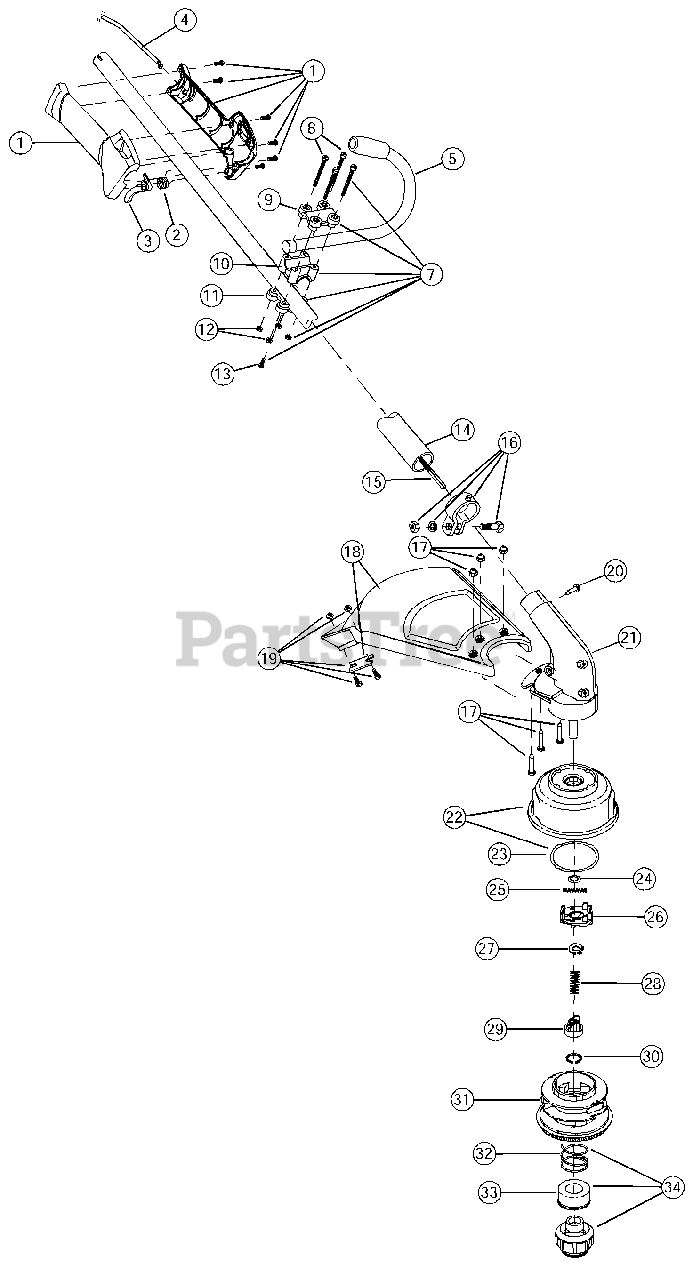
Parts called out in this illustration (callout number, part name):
1	Throttle Housing and Trigger Assembly
2	Throttle Trigger Spring
3	Throttle Trigger
4	Throttle Cable
5	J-Handle Assembly
7	Handle Bracket Assembly
9	Upper Handle Clamp
10	Middle Handle Clamp
11	Lower Handle Clamp
13	Anti-Rotation Screw
14	Drive Shaft Housing Assembly
15	Flexible Drive Shaft
16	Lower Clamp Assembly
17	Guard Mounting Screw Assembly
18	Guard & Blade Assembly
19	Blade Assembly
20	Anti-Rotation Screw
21	Gearbox Assembly
22	Outer Spool Assembly
23	Retainer
24	Thrust Washer
25	Small Spring
26	Slider
29	Plunger
31	Inner Reel
32	Large Spring
33	Foam Seal & Washer
34	Bumb Head Knob Assembly
